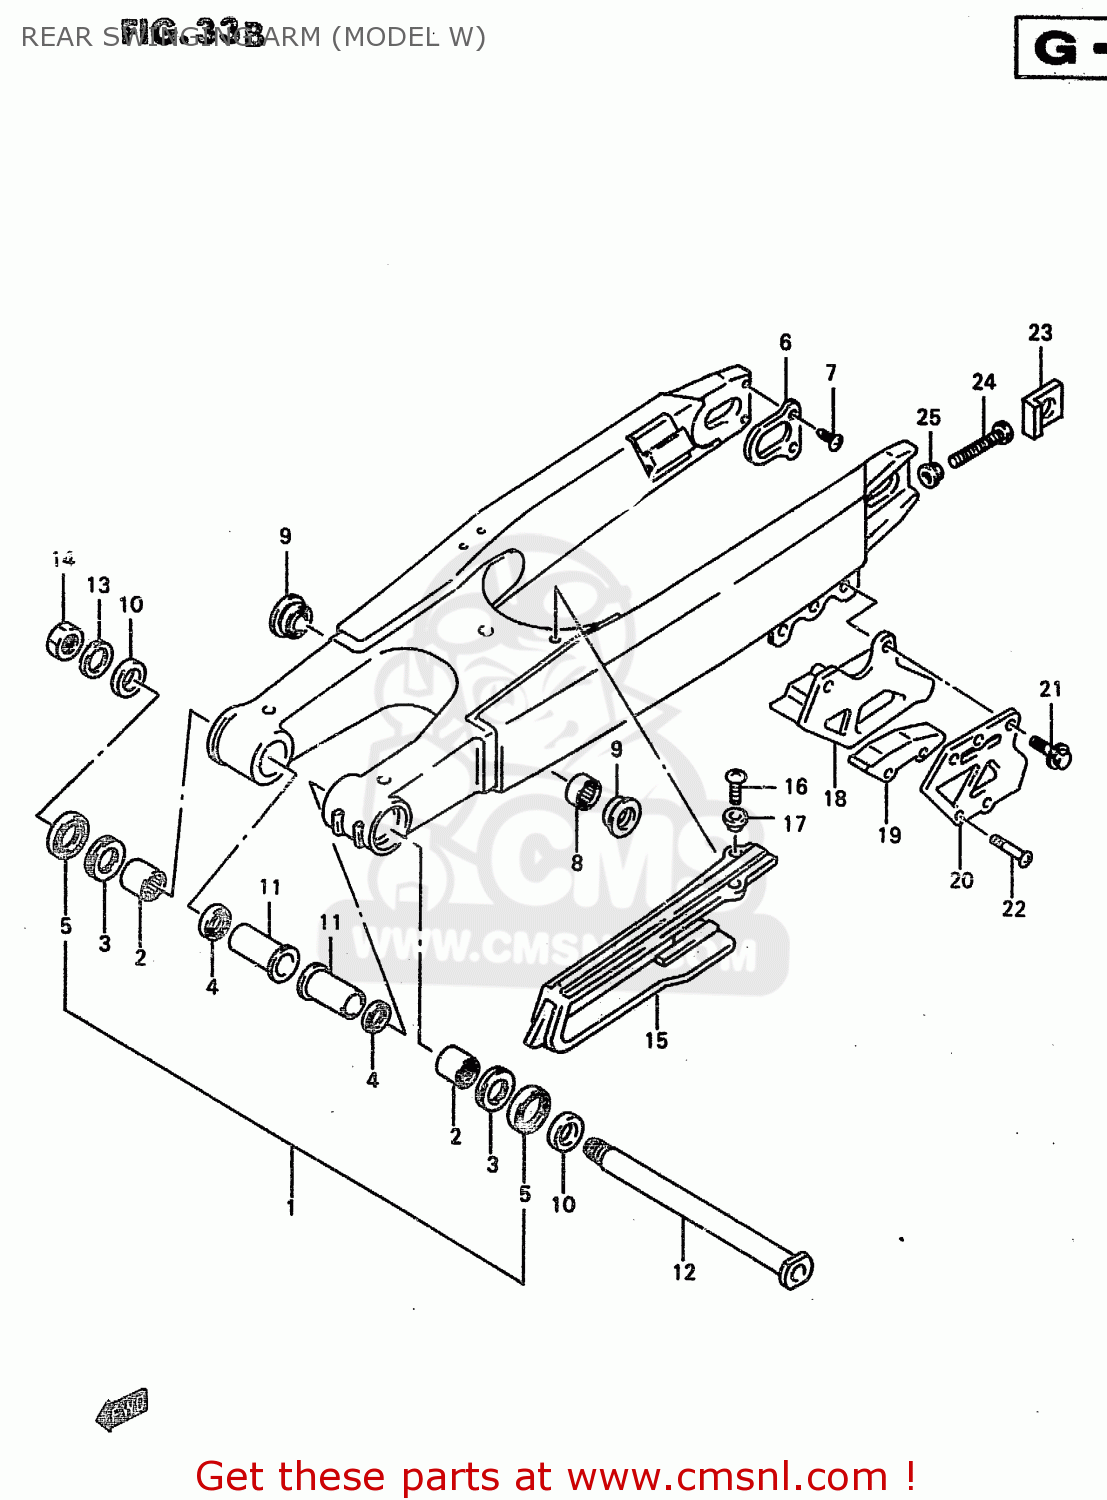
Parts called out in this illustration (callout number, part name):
1	SWING ARM ASSEMBLY,REAR
2	BEARING(22X29X30)
3	BEARING(22X35X2)
4	SEAL,OIL(22X29X4)
5	SEAL,RR SWGARM PIVOT OUTER
6	PLATE,SWING ARM RR
7	SCREW,UPPER
8	BEARING(22X28X16)
9	SEAL,SWINGING ARM RR
10	SPACER,RR SWGARM PIVOT OUTER
11	SPACER,SWGARM PIVOT INNER
12	SHAFT,RR SWINGINGARM PIVOT
13	WASHER, FIXED DRIVE FACE
14	NUT
15	BUFFER,CHAIN TOUCH DEFENSE
16	SCREW
17	WASHER
18	GUIDE,CHAIN
19	DEFENSE,CHAIN GUIDE
20	PLATE,CHAIN GUIDE OUTER
21	SCREW
22	SCREW(6X40)
23	WASHER,CHAIN ADJUSTER
24	BOLT(8X50)
25	NUT
